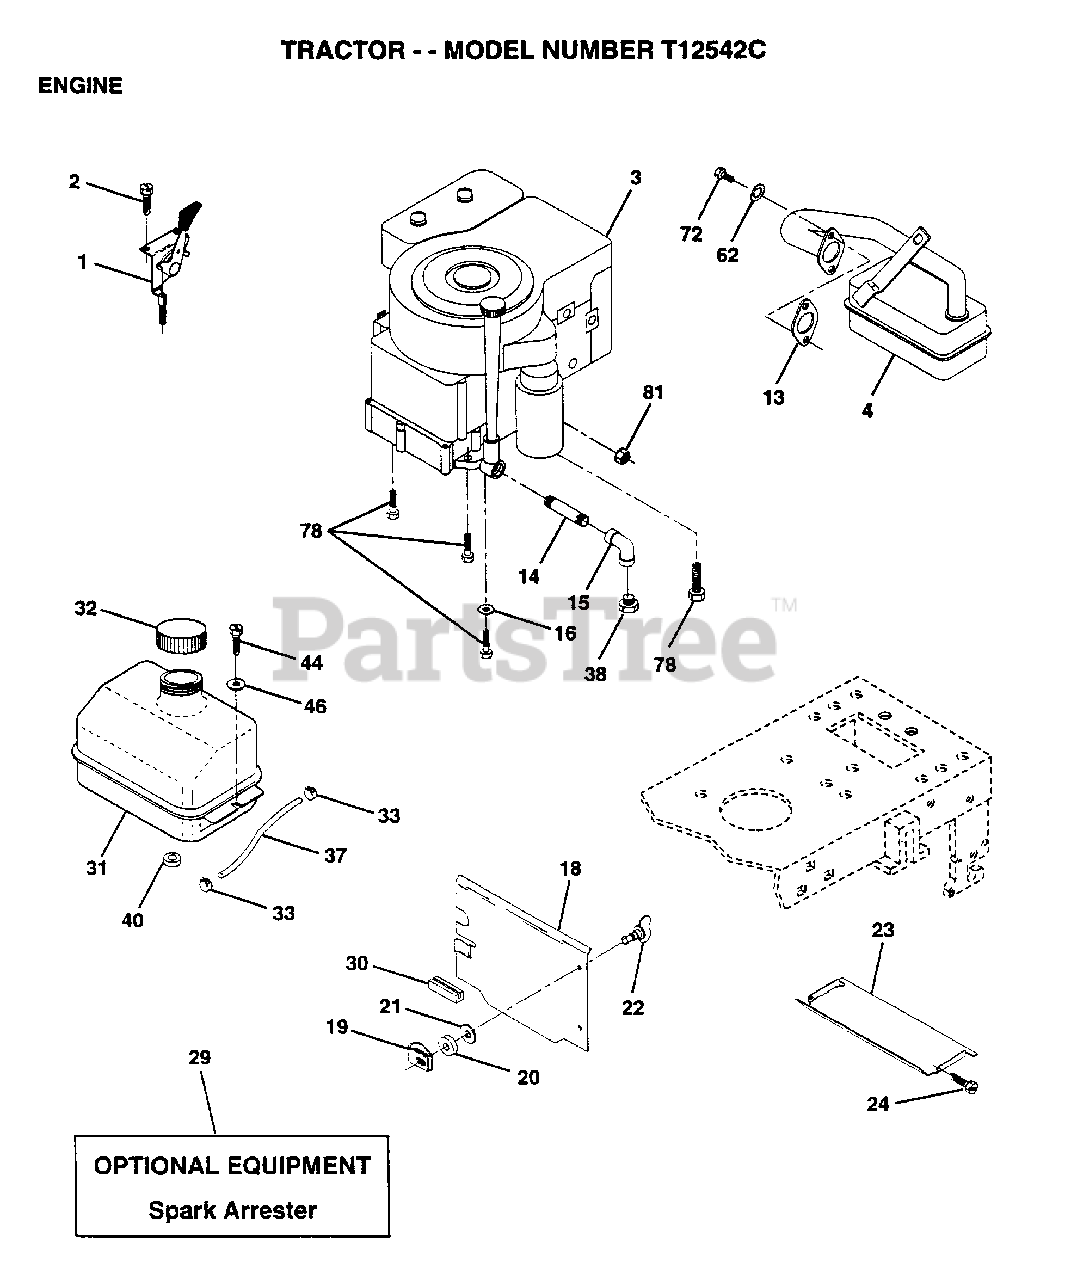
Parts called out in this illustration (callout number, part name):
1	CONTROL THROTTLE
2	SCREW LT
4	MUFFLER
14	PIPE NIPPLE
15	ELBOW
16	LOCKWASHER
18	SHIELD HEAT
19	RECEPTACLE LT
20	RECEPTACLE LT
21	WASHER
22	STUD.1/4.TURN
23	HEAT SHIELD
24	SCREW
31	TANK.FUEL.LT.
32	CAP ASM FUEL
33	HOSE CLAMP
37	LINE FUEL
44	SCREW HEX CRT
46	WASHER
62	LOCKWASHER
72	SCREW
78	SCREW
81	NUT
